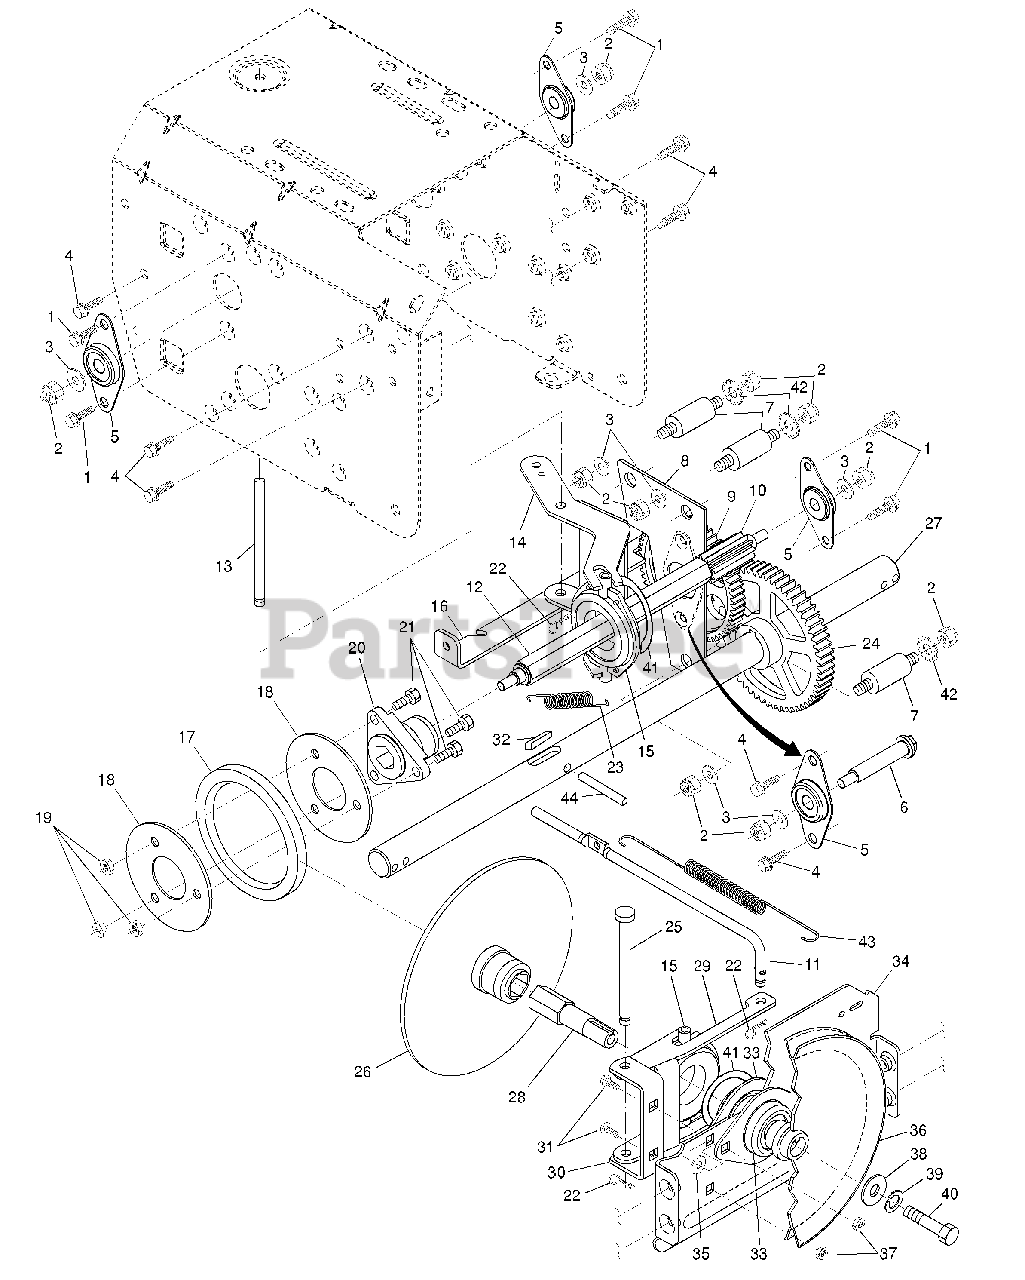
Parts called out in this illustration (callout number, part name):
1	Screw, Hex Head 5/16-18 x 3/4
2	Nut, Lock 5/16-18
3	Washer, Flat
4	Screw, Hex Head 5/16-18 x 1/2
5	Bearing, Flange
6	Shaft, Auxiliary
7	Spacer, Plate
8	Plate, Auxiliary
9	Gear, Intermediate
10	Gear, Pinion
11	Rod, Clutch
12	Shaft, Long, Hex
13	Pin, Pivot
14	Lever, Shifter / Wheel
15	Trunnion Bearing Assembly
16	Bracket, Pivot, Shift
17	Ring, Rubber Wheel
18	Plate, Rubber Wheel
19	Nut, Lock 5/16-18
20	Hub, Rubber Wheel
21	Screw, Hex Head 5/16-18 x 7/8
22	Retainer, Hairpin
23	Spring, Bias
24	Gear, Axle
25	Pin, Pivot Lever
26	Plate Assembly, Drive
27	Shaft, Axle
28	Shaft, Short Hex
29	Lever, Shifter Plate
30	Bracket, Shifter Support
31	Bolt, Carriage 5/16-18 x 5/8
32	Key, Square
33	Bearing, Flange
34	Plate, Drive Mounting
35	Spacer, Bearing
36	Pulley, Traction Drive
37	Nut, Lock 5/16-18
38	Washer, Flat
39	Washer, Lock 5/16
40	Screw, Hex Head 5/16-18 x 3/4
41	Ring, Retaining
42	Washer, Lock, External Tooth 5/16
43	Spring, Return
